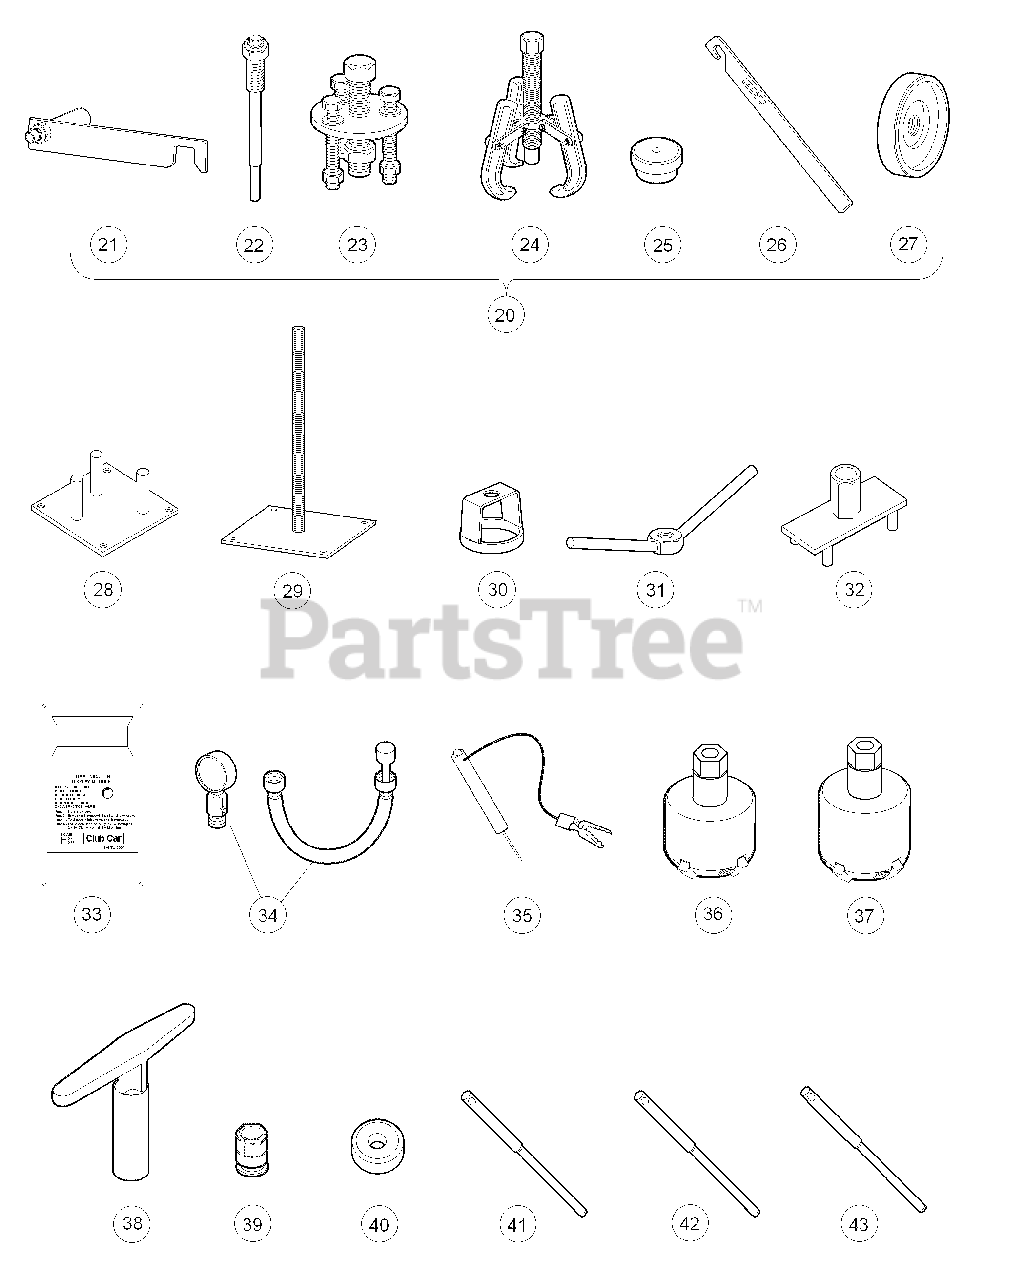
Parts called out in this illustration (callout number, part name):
20	Clutch Tool Kit
21	Clutch Alignment Tool
22	Drive Clutch Puller
23	Drive Clutch Hub Puller
24	Driven Clutch Cam Puller
25	Driven Clutch Puller Plug
26	Drive Clutch Holder Tool Assembly
27	Press Weldment
28	Drive ClutchFixed Sheave Tool
29	Driven Clutch Spring Compression Base
30	Driven Clutch Spring Compression Collar
31	Driven Clutch Spring Compression Nut
32	Drive Clutch Spider Removal Tool
33	Communication Display Module
34	Compression Gauge and Adapter
35	Continuity Tester
36	Cutter, Valve Seat, #122
37	Cutter, Valve Seat #115
38	Wrench, T, #505
39	Adapter, T-Wrench
40	Cutter, Valve Seat, 60 Degree
41	Pilot, 6.6 MM
42	Pilot, 6.62 MM
43	Pilot, 6.65 MM
